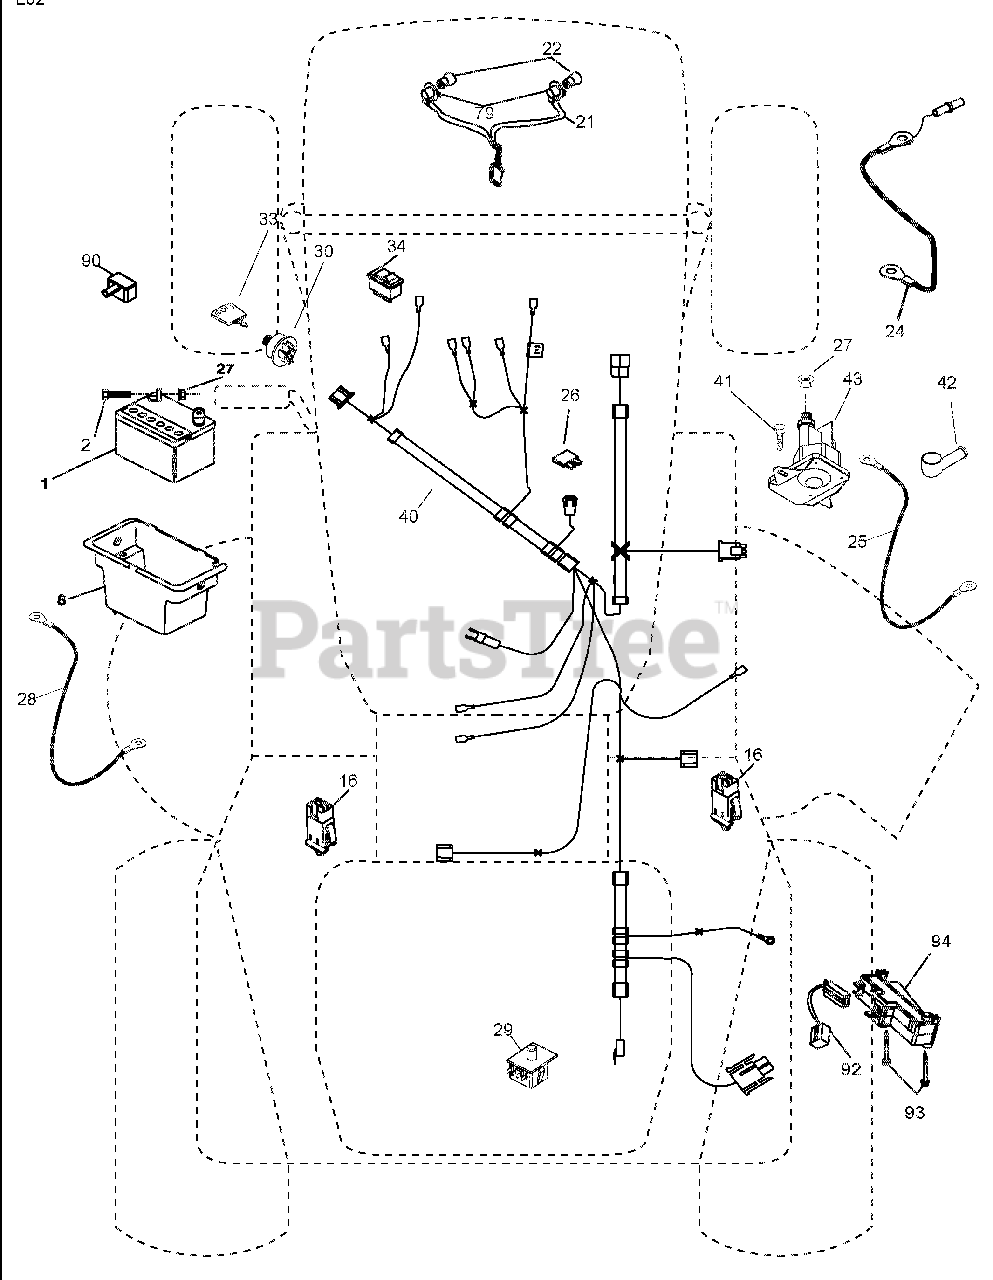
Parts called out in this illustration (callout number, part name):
1	BATTERY.12.VOLT.28.AMP.WET
2	BOLT.HEX.HD.1/4-20UNC X 3/4
8	Box Battery
16	SWITCH.INTERLOCK.NONO.GRAY
21	HARNESS ASM.LIGHT.22"(4152J)
22	HARNESS ASM.LIGHT.22"(4152J)
24	Cable Battery
25	Cable Battery 6 Ga. 11" Red
26	FUSE.20 AMP.
27	Nut, Keps Hex 1/4-20 unc
28	Cable Ground 6 Ga. 12" Black
29	SWITCH.SEAT.DP.W/ROS
30	SWITCH.IGN.DLTA.P-IN.ROS
33	KEY/CHAIN.BLISTER PACK.GEN.CE
34	SWITCH.LIGHT/RESET.B/B/RED.
40	Harness Ign
41	Bolt Blk Fin Hex 1/4-20
42	COVER.TERMINAL.RED
43	SOLENOID.W/BRASS PLUNGER.2005
79	SOCKET ASM.BULB.TWISTLOCK
90	COVER.TERMINAL.BATTERY.RR.TEX
92	HARNESS.PIGTAIL.CONSLE.ROS.MLK
93	SCREW.PLASTITE.10-14 X 2.0
94	MODUAL REVERSE ROS
